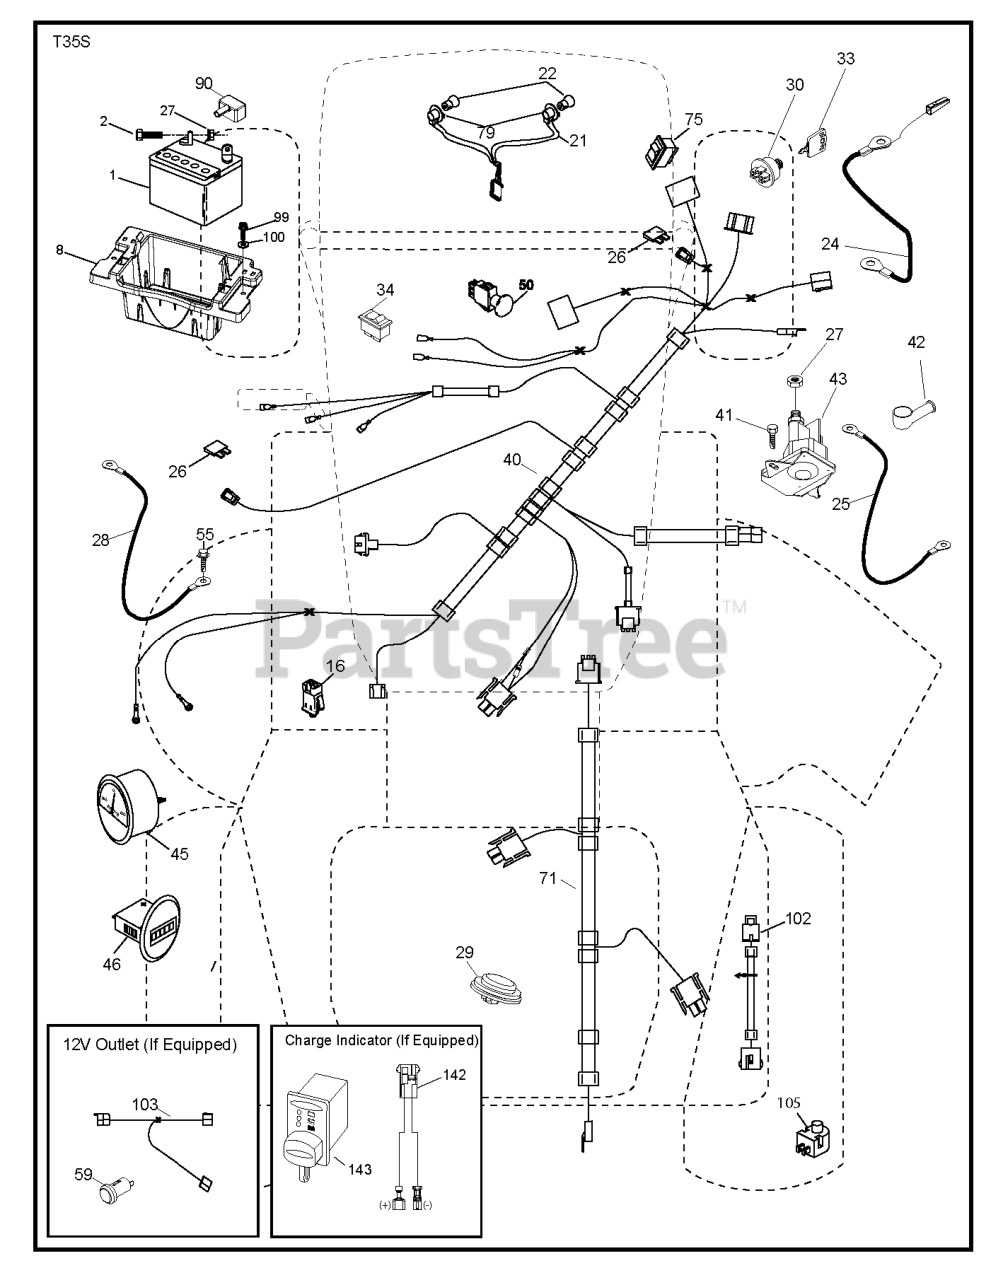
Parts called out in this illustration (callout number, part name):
1	Battery, Dry 30 Amp
2	BOLT.HEX.1/4.X.3/4.DICHROMATE
8	BOX.BATTERY.MOUNT.FRONT.LT
16	SWITCH INTERLOOK PUSH-IN
21	HARNESS.LIGHT W/4152J BULBS
24	CABLE.FRBATT.W/WIRE.8GA.8
25	CABLE.STARTER.6G.BL/RED.17.5
26	FUSE 20AMP
27	NUT
28	CABLE.GROUND.21"BLK.8GA.90T
29	SWITCH.SEAT.DELTA.OPC.
30	SWITCH.IGN.DELTA.W.LGH.ROS
33	KEY.CHAIN.BLISTER.PACK.GEN.USA
40	HARNESS.DASH.EDIFF.RND.CHG
41	SCREW
42	TERMINAL COVER
43	SOLENOID.W/BRASS.PLUNGER
45	AMMETER GAUGE ROUND SNAP-IN
46	HOURMETER.GAUGE.RNK.SNAP.LS
50	RP.PTO.SWITCH.8 TERMINAL.BLACK
55	SCREW 5/16"
59	OUTLET.12-VOLT
71	HARNESS.IGN.CHASSIS.TEX.DCKLOC
75	SWITCH.ON/OFF.(DIFF.LOCK)
79	BULB HOLDER ASM.
90	COVER.TERMINAL.BATTERY
91	STRAP.BATTERY.MOUNT.FRONT(2 2)
99	SCREW HEXWSHR 1/4-20X3/4
100	WASHER
102	HARNESS PIGTAIL PCH TEX ROS
103	HARNESS.PIGTAIL.12V.OUTLET.
105	REVERSE SWITCH
142	CHARGE.PORT.PIGTAIL HARNESS
143	CHARGE.PORT
